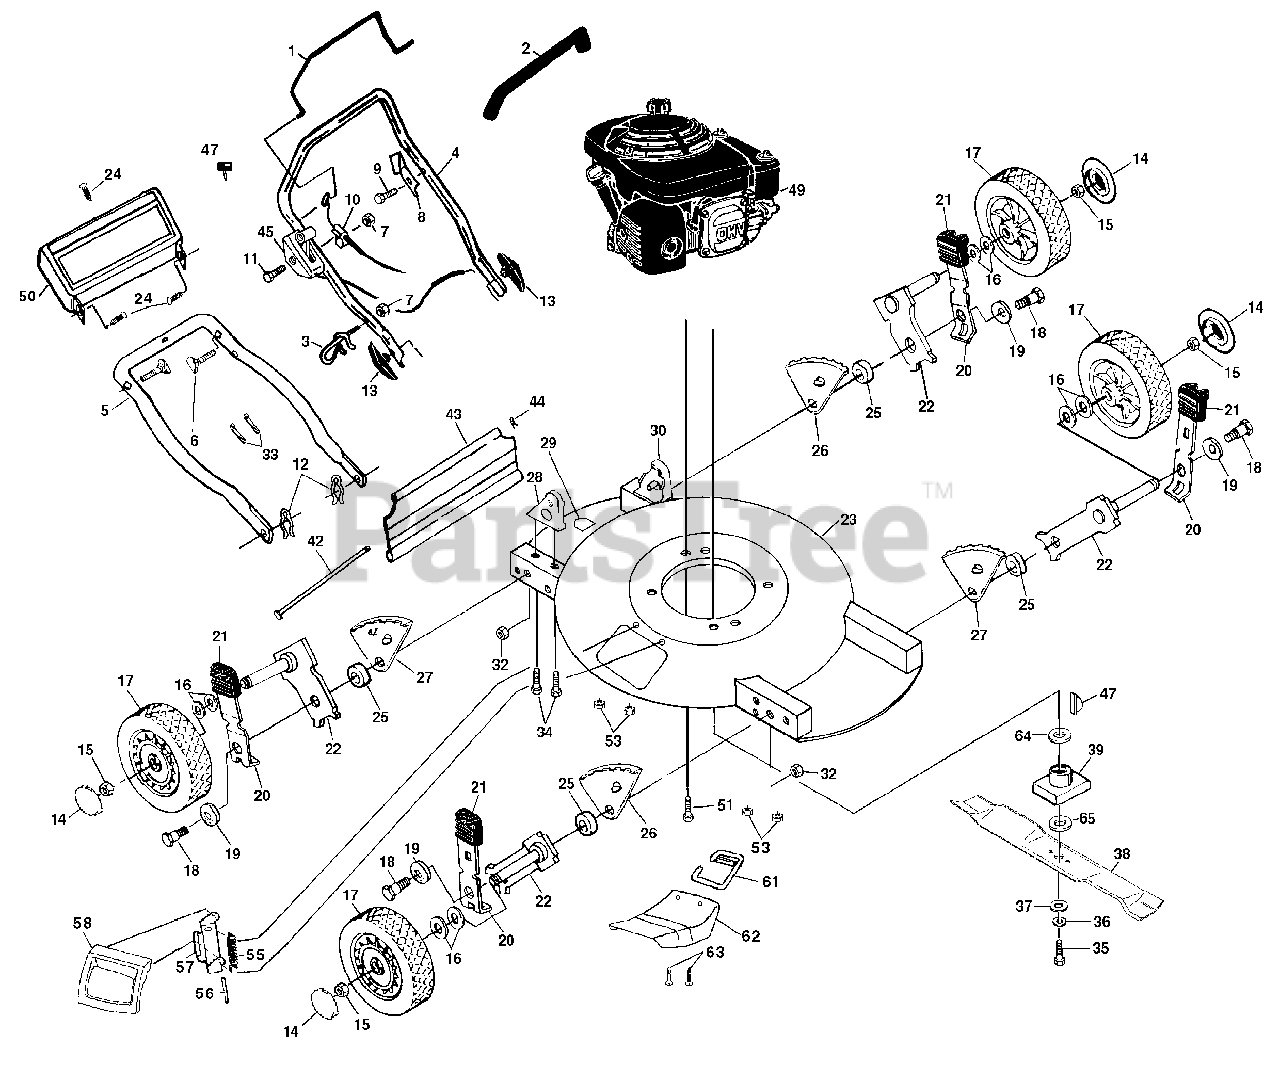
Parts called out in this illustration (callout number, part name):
1	Control Bar
2	Handle Grip
3	Rope Guide
4	Upper Handle
5	Lower Handle
6	Handle Bolt 5/16-18 x 1-3/4
7	Locknut 1/4-20
8	Up-Stop Bracket
9	Hex Washer Head Screw #10-24 x 1/2
10	Engine Zone Control Cable
11	Hex Washer Head Screw 1/4-20 x 2.12
12	Hairpin Cotter
13	Handle Knob
15	Hex Locknut 3/8-16
16	Washer
17	Wheel & Tire Assembly
18	Shoulder Bolt
19	Belleville Washer
20	Selector Spring
21	Selector Knob
22	Axle Arm Assembly
23	Lawn Mower Housing
24	Push-in Fastener
25	Spacer
26	Wheel Adjusting Bracket (R.F./L.R.)
27	Wheel Adjusting Bracket (L.F./R.R.)
28	Handle Bracket Assembly (Right)
29	Danger Decal
30	Handle Bracket Assembly (Left)
32	Locknut 3/8-16
33	Wire Ties
34	Thread Cutting Screw 5/16-18 x 3/4
35	Hex Head Screw 3/8-24 x 1-3/8
36	Helical Lockwasher 3/8
37	Hardened Washer
39	Blade Adapter
42	Deflector Rod
43	Rear Deflector
44	Retainer Clip
45	Throttle Control
50	Trim Plate
51	Hex Head Screw, Self Tap. 3/8 - 16 x 1.1
53	Locknut
55	Torsion Spring
57	Housing Assembly Bracket
58	Mulcher Door
61	Chute Mounting Bracket
62	Mulcher Deflector
63	Truss Head Screw
64	Washer
